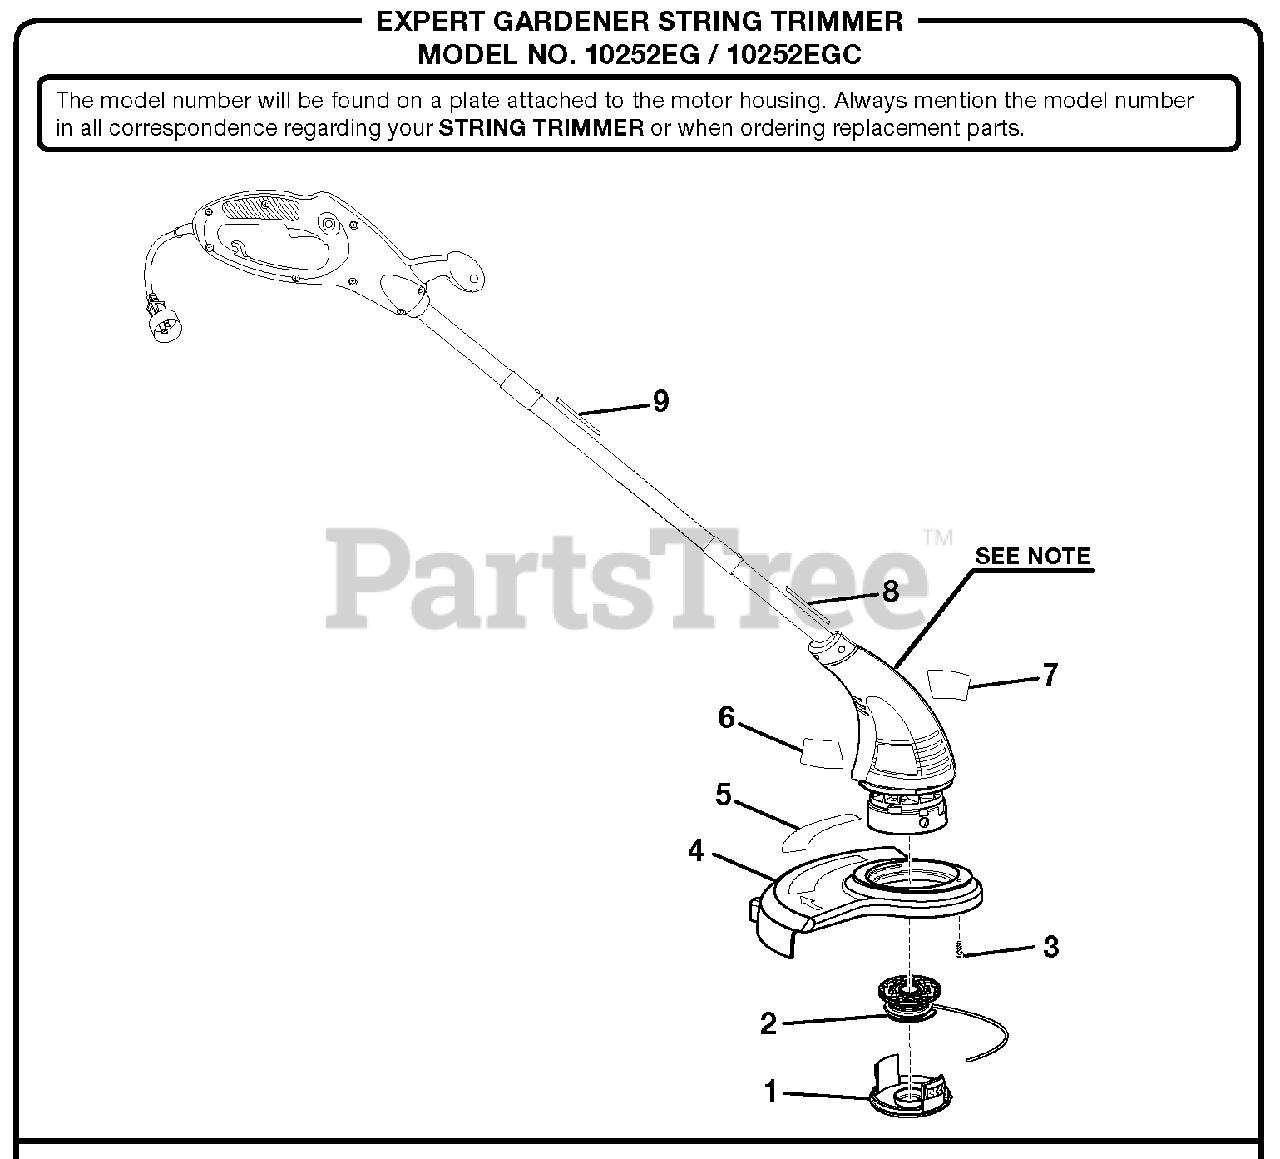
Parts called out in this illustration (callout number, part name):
1	Spool Cap
2	Spool w/Line
3	Screw (M4 x 16 mm)
4	Grass Shield
5	Guard Label
6	Data Label
7	Logo Label
8	Warning Label
9	Warning Icon Label
